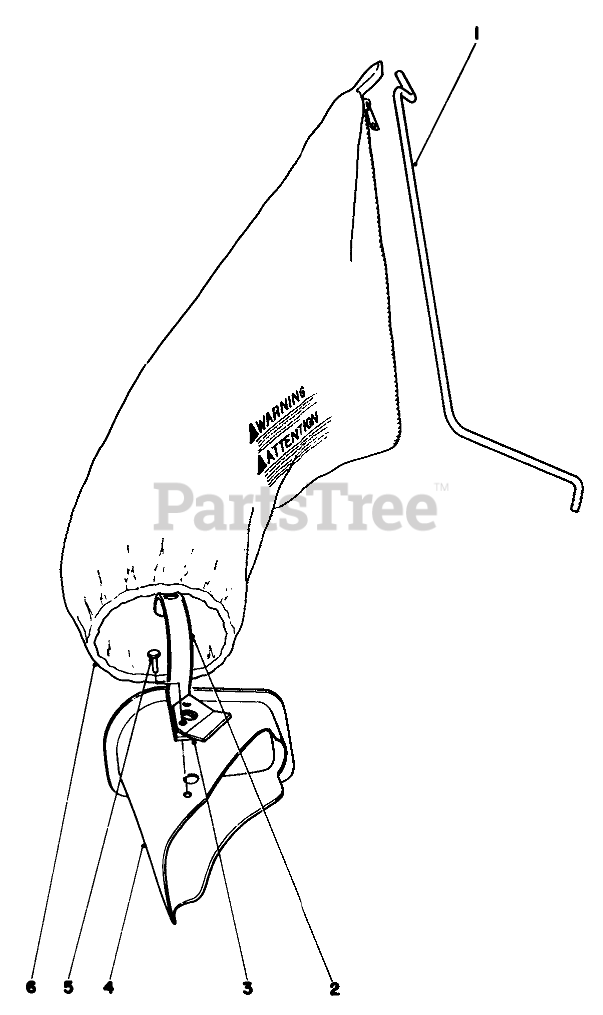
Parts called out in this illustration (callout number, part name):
1	BAG HANGER ROD
2	BAG CHUTE HANDLE
3	Stop Deflector
4	Grass Chute (Incl. Ref. #2 & 5)
5	Rivet Semi Tubular
6	BAG REPLACMNT44-0540
